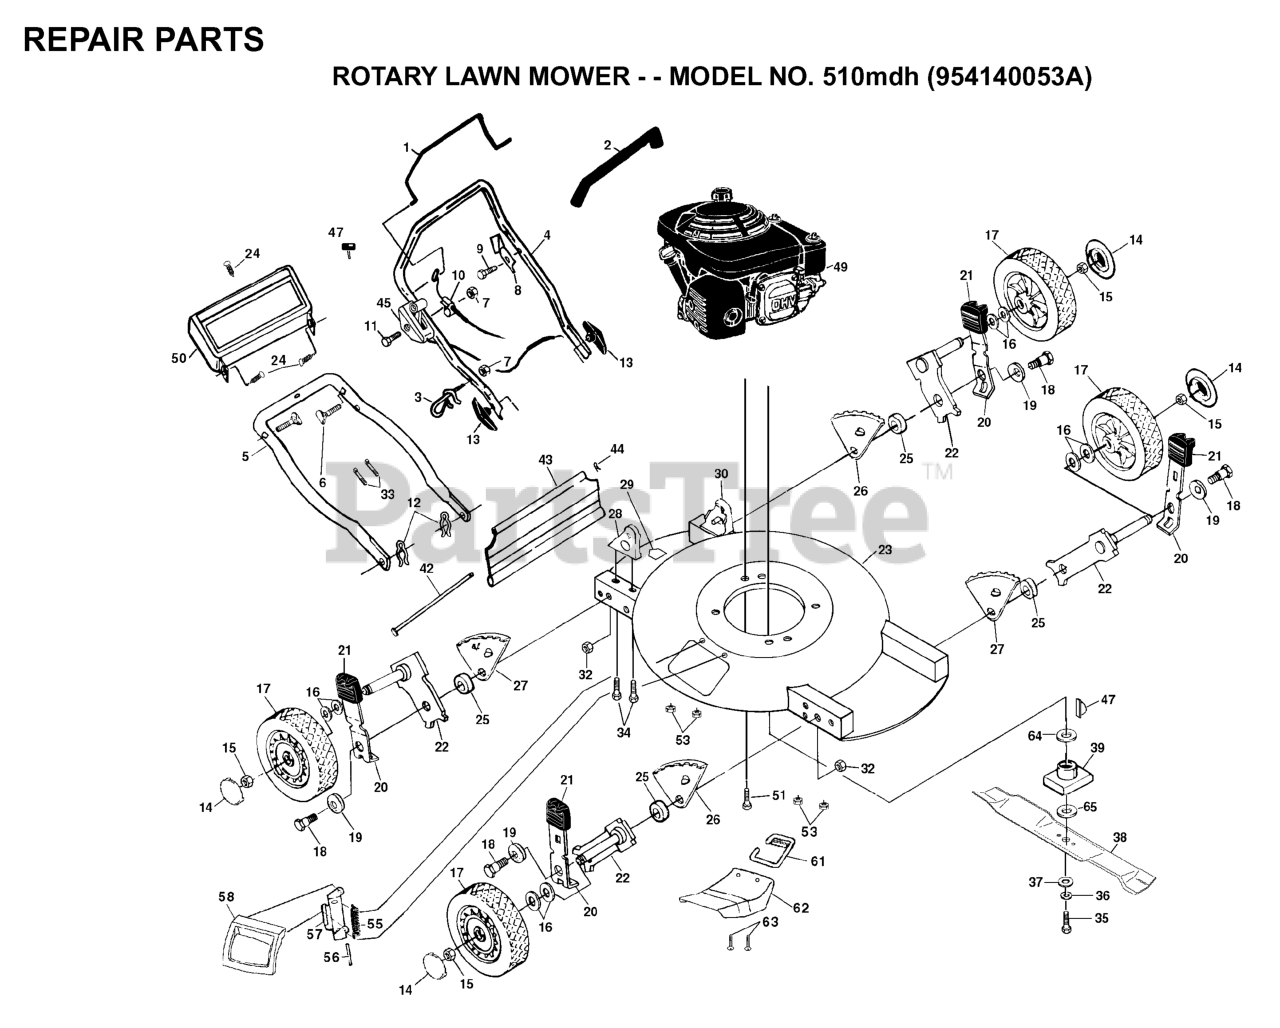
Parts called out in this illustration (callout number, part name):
1	CONTROL BAR/BLACK
2	GRIP.HANDLE.FOAM
3	ROPE GUIDE
5	HANDLE, LOWER
6	HANDLE BOLT
7	NUT
8	BRACKET UPSTOP
9	TAPPING SCREW
10	CABLE
11	SCREW 1/4-20 X 2.12
12	HAIRPIN COTTER
13	HANDLE KNOB
14	HUB CAP PM
15	HEX FLANGE LOCKNT
16	WAVE WASHER
17	WHEEL & TIRE
18	BOLT
19	WASHER.BELLEVILLE (3 2 LB)
20	SELECTOR SPRING
21	SELECTOR KNOB
22	AXLE ARM
25	RP SPACER HT ADJ
26	WHL ADJ BRKT RF/LR
27	WHL ADJ BRKT LF/RR
28	HDLE BRKT ASSY RH
29	DECAL HYT
30	HDLE BRKT ASSY LH
32	LOCKNUT PM
33	TIE GUIDE
34	SCREW.5/16-18X3/4
35	SCREW, HEX HD 3/8-24 X 1-3/8
36	LOCKWASHER
37	WASHER,HARDEN
38	BLADE.20.MULCH.(50DK,6020MD)
44	RETAINER CLIP
47	HI PRO KEY PM WSL
50	TRIM PLATE
51	BOLT 3/8-16X1-1/8
53	NUT
55	TORSION SPRING
56	ROD.HINGE.COMBI-C
57	BRACKET PM
58	MULCHER DOOR
61	BRACKET.CHUTE.MTG
62	MULCHER DEFLECTOR
63	Truss Head Screw
64	WASHER
